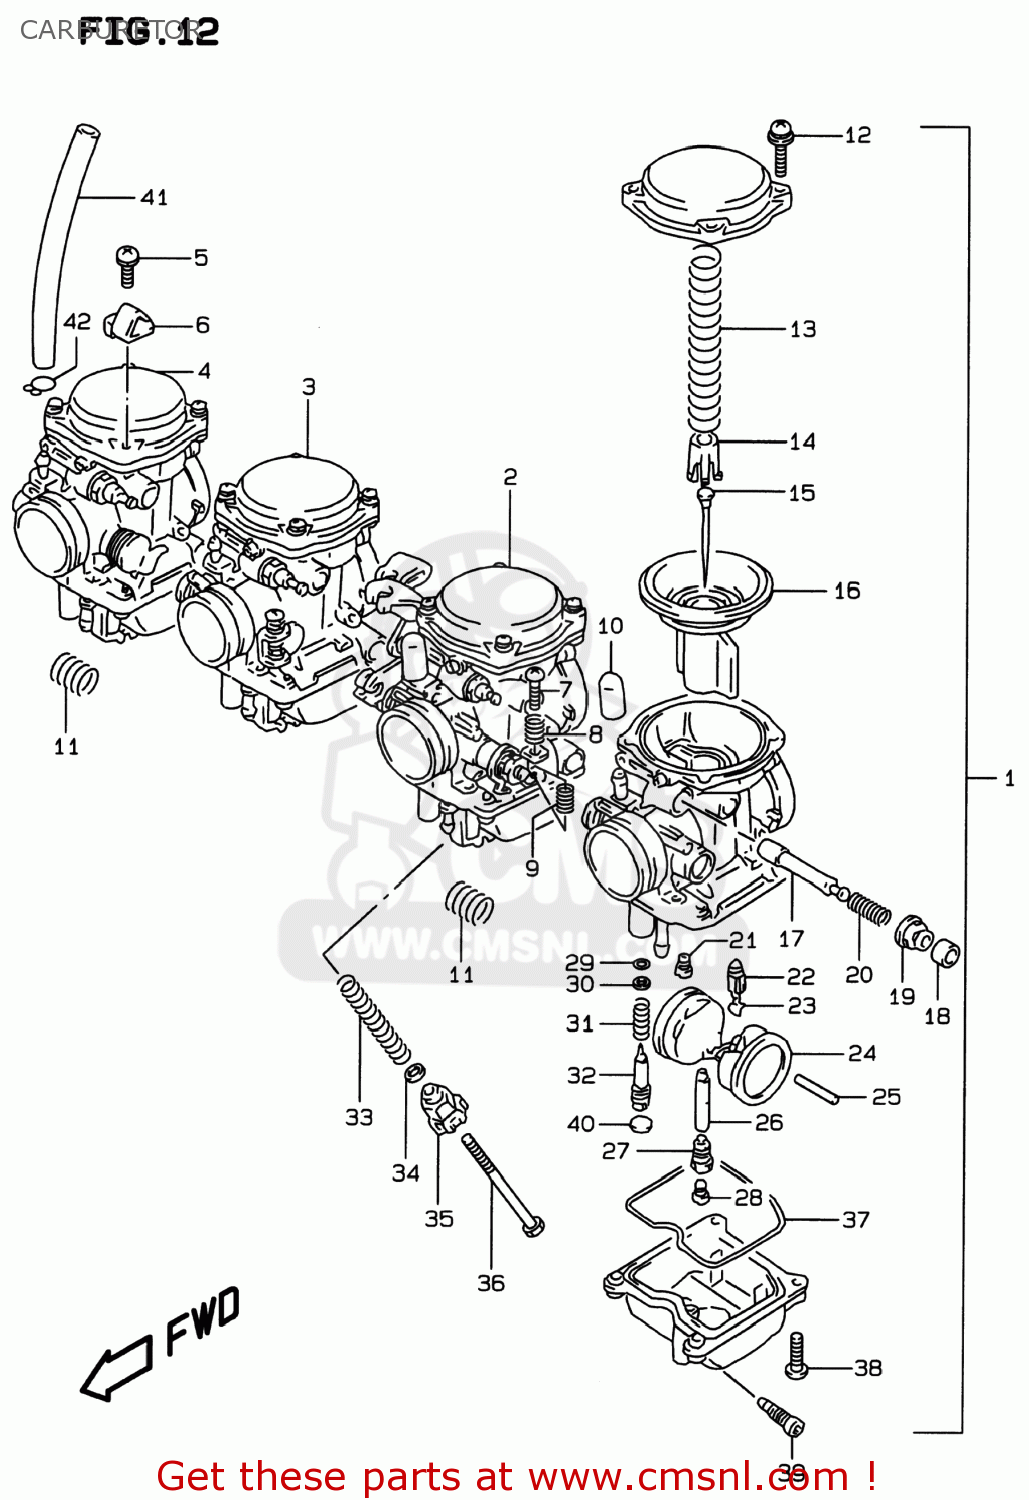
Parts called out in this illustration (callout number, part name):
1	CARBURETOR ASSEMBLY,LEFT
2	CARBURETOR ASSEMBLY,MIDDLE,LEFT
3	CARBURETOR ASSEMBLY,MIDDLE,RIGHT
4	CARBURETOR ASSEMBLY,RIGHT
5	SCREW
6	STAY,PLATE
7	SCREW
8	SPRING
9	SPRING
10	CAP
11	SPRING
12	SCREW
13	SPRING
14	SEAT,SPRING
15	NEEDLE,JET(N1QA)
16	PISTON
17	VALVE,STARTER
18	CAP
19	CAP
20	SPRING
21	JET,SLOW(35)
22	VALVE ASSY,NEEDLE
23	CLIP
24	FLOAT ASSY
25	PIN,FLOAT
26	JET,NEEDLE
27	HOLDER,NEEDLE JET
28	JET,MAIN(98)
29	O RING
30	WASHER
31	SPRING
32	SCREW,PILOT
33	SPRING
34	WASHER
35	HOLDER,ADJUST
36	BOLT
37	O RING
38	SCREW
39	PLUG,DRAIN
40	CAP
41	HOSE(5X9X600)
42	CLIP
